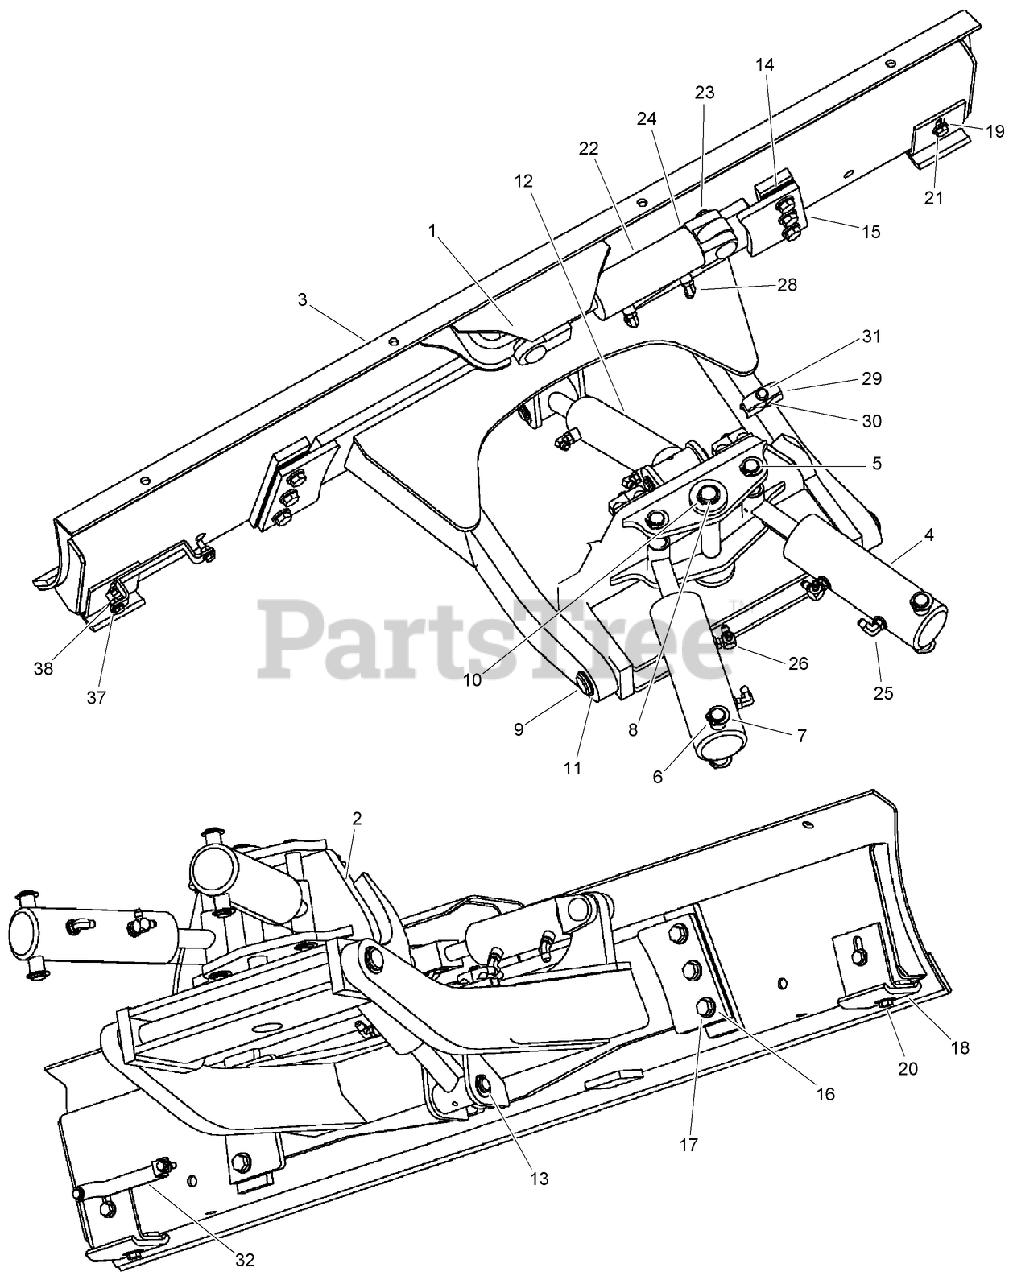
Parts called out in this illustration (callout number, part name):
1	WELDMENT-Backfill Blade Frame
2	WELDMENT-Backfill Blade Pivot
3	WELDMENT-Backfill Blade
4	HYD CYLINDER ASM
5	PIN-LINK
6	PIN-LINK
7	RING-Retainer
8	PIN-Pivot
9	PIN-Frame
10	RING-RETAINING
12	HYD CYLINDER ASM
13	PIN-CYLINDER
14	SHIM-Retainer
15	RETAINER-Blade
16	WASHER-FLAT
17	BOLT-Hex Hd 5/8 x 1-1/2 GR5 ZND
18	WELDMENT-Skid Shoe
19	WASHER-FLAT
20	BOLT-Hex Hd 1/2 x 1-3/4 GR5 ZND
21	BOLT-Hex Hd 1/2 x 1-1/4 GR5 ZND
22	CYLINDER ASM-63.5 (2-1/2) id X 89 MM (3-1/2 INCH) stroke, backfill blade tilt
23	PIN-HEADED
24	PIN-Cotter 0.25 x 2.00 in ZN
25	ELBOW-90 DEG (ADJUSTABLE 37 DEG)
26	FITTING
28	ELBOW-45 Adj 37FL 3/8 Tube
30	NUT-SQUARE
31	BOLT
32	BRACKET-Hose
37	WASHER-FLAT
38	NUT-Serr Flg 3/8-16 UNC GR5 ZND
